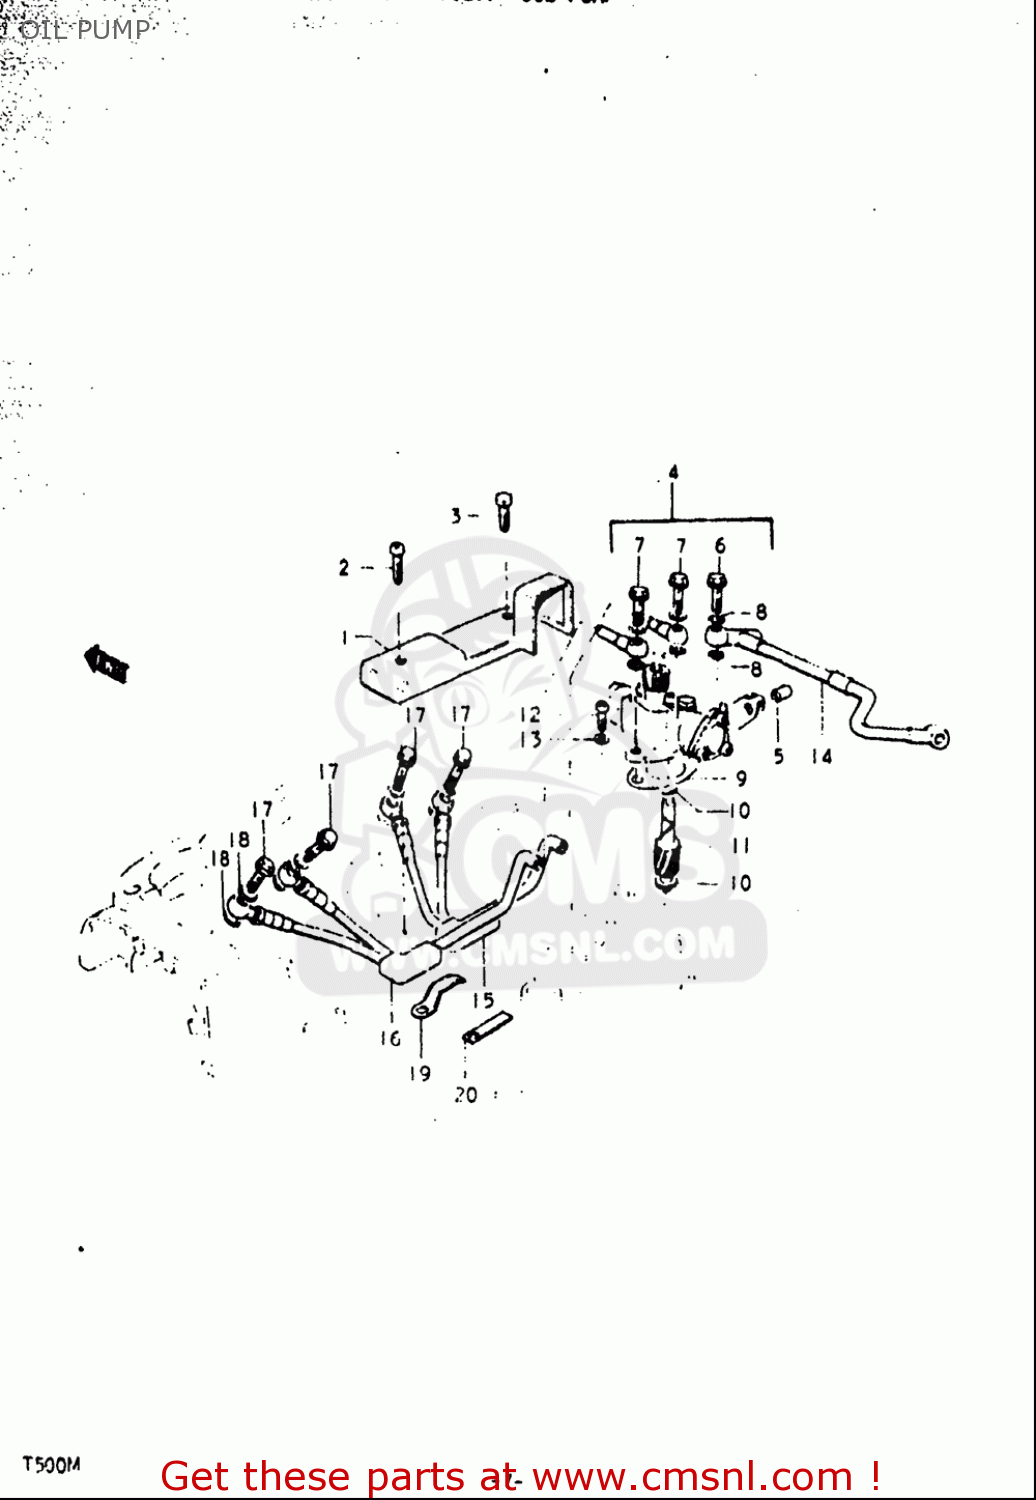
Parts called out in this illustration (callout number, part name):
2	SCREW
3	BOLT
5	TERMINAL, CABLE
6	UNION BOLT
7	UNION
8	GASKET(6.2X11X1).2 (NAS)
10	WASHER(8X13.7X1)
12	SCREW
13	WASHER,LOCK
17	UNION BOLT
18	GASKET(6.2X11X1).2 (NAS)
19	CLAMP
